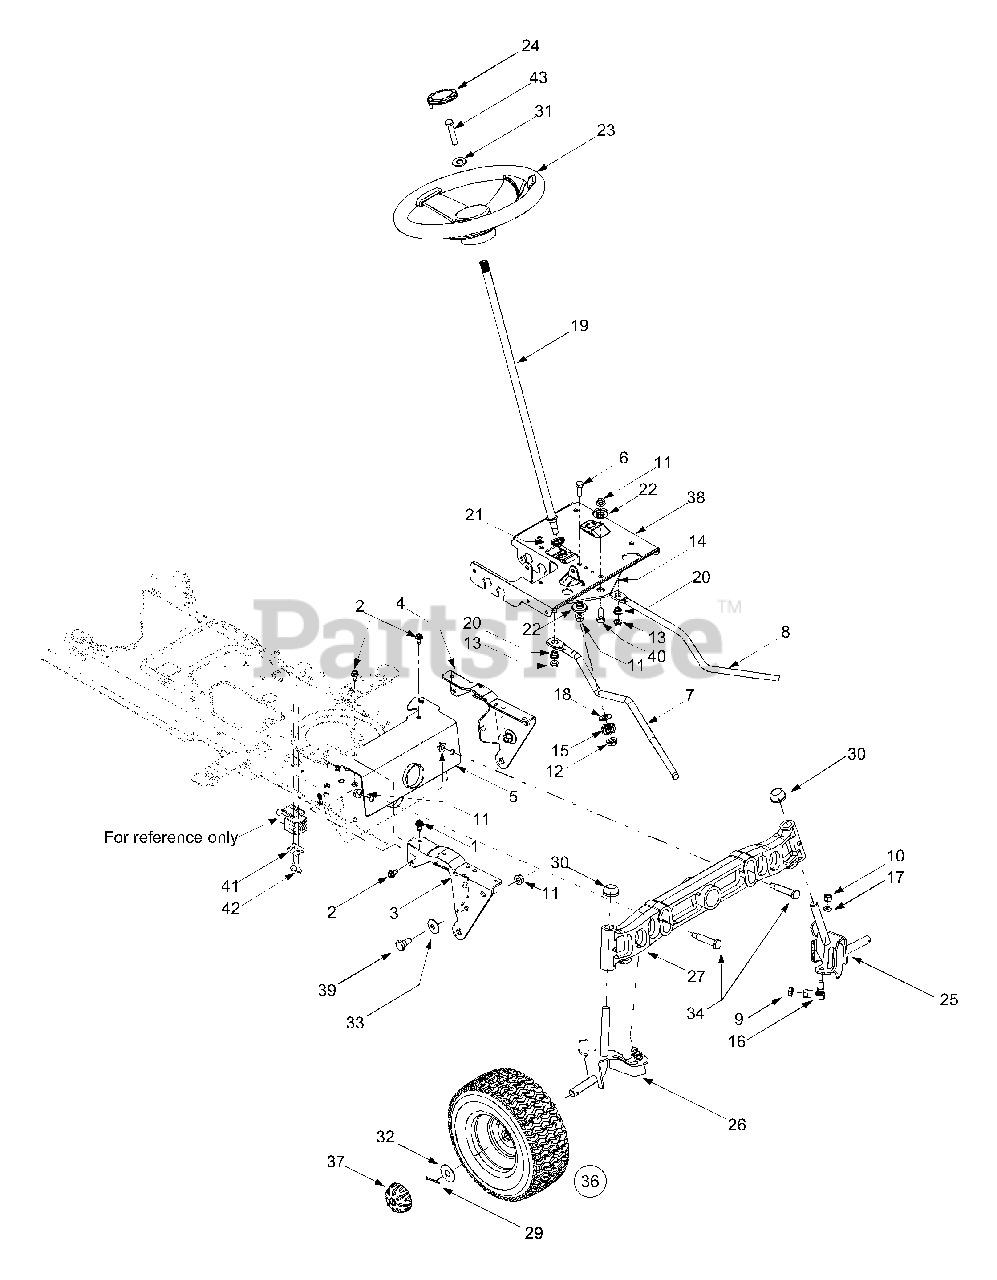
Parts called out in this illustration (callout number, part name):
1	Self-Tapping Screw, 5/16-18 x .75
2	Self-Tapping Screw, 16-18 x .625
6	Hex Cap Screw, 3/8-16 x 1
7	RH Drag Link
8	LH Drag Link
9	Jam Nut, 7/16-20
10	Center Lock Nut, 3/8-24
11	Lock Nut, 3/8-16
12	Flange Lock Nut, 7/16-20
13	Lock Nut, 5/16-18
14	Steering Gear
15	Steering Pinion Gear
16	Ball Joint, 7/16-20
17	Lock Washer, 3/8
18	Flat Washer, .51 x 1.12 x .06
19	Steering Shaft, .625 OD x 24.4
20	Plastic Bushing, .38 ID
21	Hex Flange Bearing, 5/8
22	Shoulder Spacer, .38 ID
23	Steering Wheel: 3 Spoke
24	Steering Wheel Cap
25	LH Axle Assembly
26	RH Axle Assembly
27	Cast Iron Pivot Bar w/ Fittings
29	Cotter Pin
30	Push Cap
31	Flat Washer
32	Flat Washer
33	Bell Washer
34	Shoulder Screw, .5 x 2.2, 3/8-16
35	Hex Bolt, 5/16-18 X 1
37	Hub Cap
39	Shoulder Screw, 3/8-16
40	Hex Screw3/8-16 x 1.0
41	Switch Plate
42	AB Screw #10-16 x 0.5
